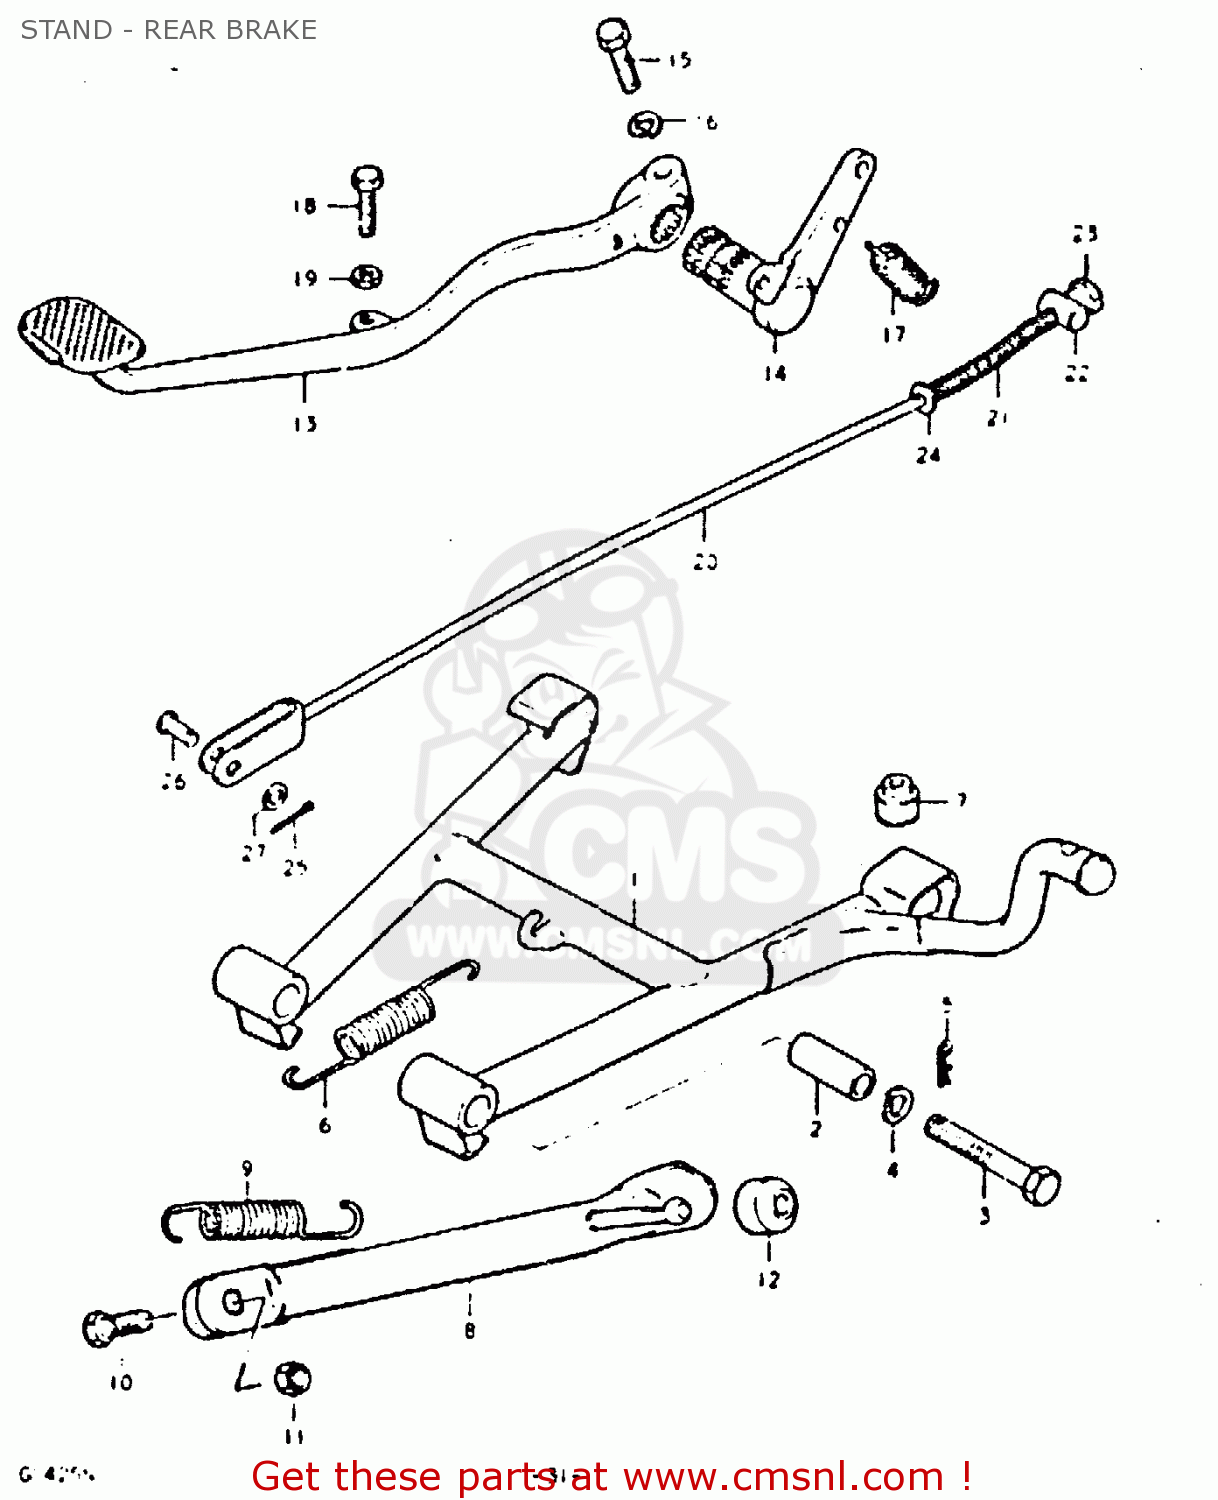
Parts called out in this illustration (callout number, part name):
1	STAND,CENTER
2	SPACER(10X16X38.8)
3	BOLT
4	LOCK WASHER
5	CLIP
6	SPRING
7	CUSHION
8	STAND,SIDE
9	SPRING
10	BOLT(10X30)
11	NUT
12	CUSHION
13	PEDAL,BRAKE
14	ARM,BRAKE PEDAL ROD
15	BOLT
16	LOCK WASHER
17	SPRING
18	BOLT
19	NUT
20	ROD ASSEMBLY,REAR BRAKE
21	SPRING
22	PIN
23	NUT
24	WASHER
25	PIN 20X20
26	PIN(L:13.5)
27	WASHER
